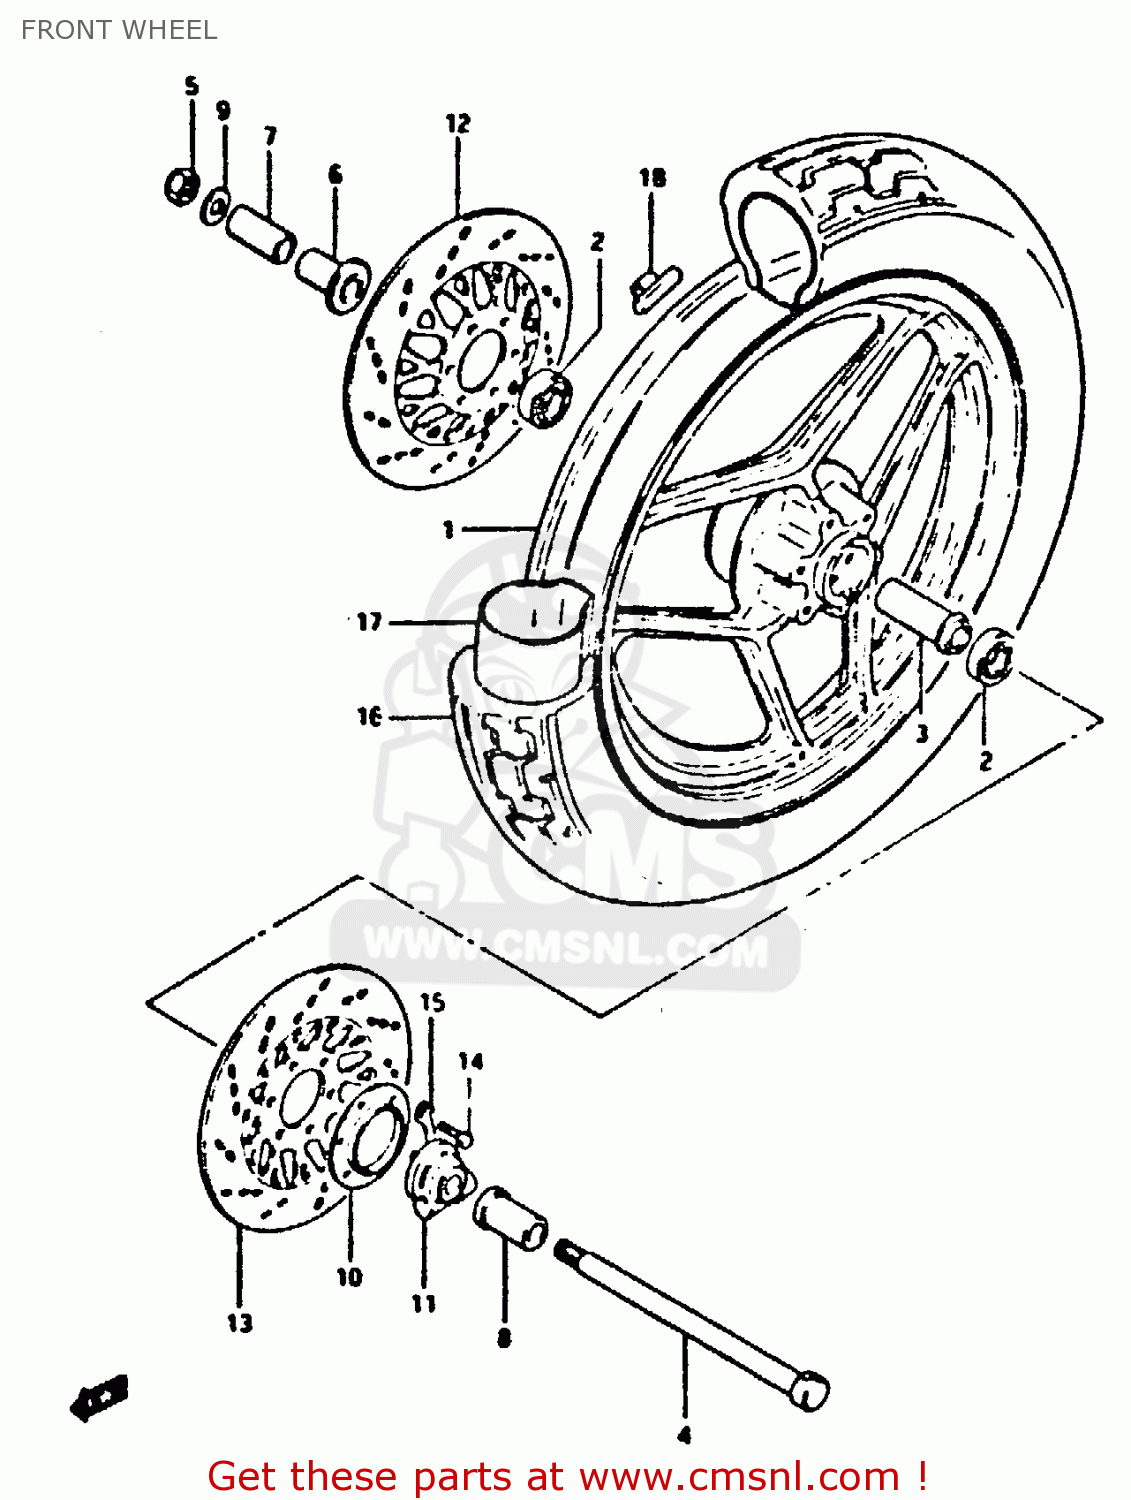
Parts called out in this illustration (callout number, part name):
1	CASTING WHEEL,FRONT 2.15
2	BEARING
3	SPACER,FRONT HUB BEARING
4	AXLE,FR
5	NUT
6	SPACER,FR AXLE,R
7	SPACER,FR AXLE,R
8	SPACER,FR AXLE,L
9	WASHER
10	DUST SEAL,SPEEDOMETER GEAR BOX
11	BOX ASSEMBLY,SPEEDOMETER GEAR
12	DISC,BRAKE,RIGHT
13	DISC,BRAKE,LEFT
14	BOLT(8X28)
15	WASHER
16	TIRE,FRONT
17	TUBE,INNER
18	BALANCER,WHEEL
